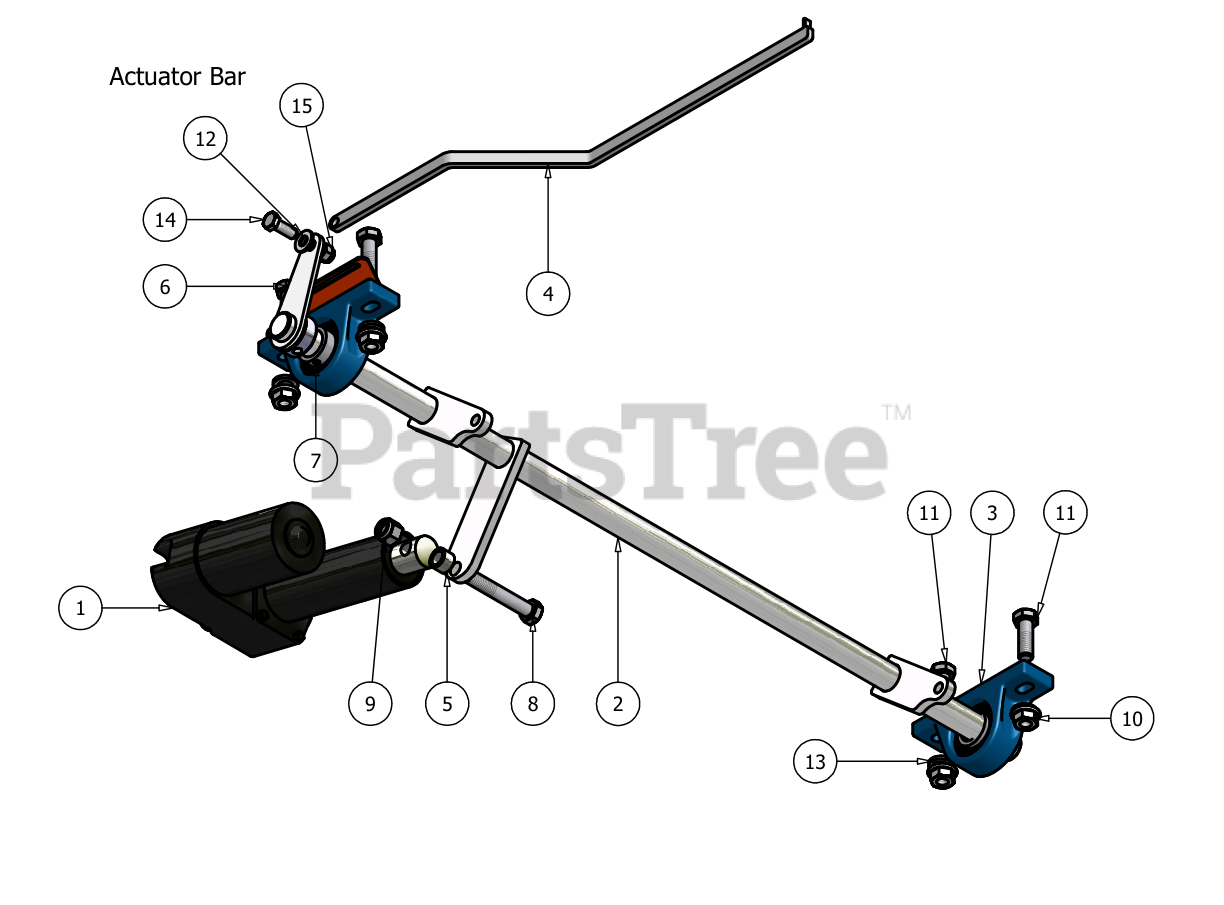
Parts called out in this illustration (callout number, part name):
2	Actuator Bar
3	1" Pillow Block
4	Height Indicator
5	1/2" x 1/2" Collar Spacer
6	2006 Height Indicator Lever
7	3/8" Set Screw
8	1/2" x 3" Hex Bolt
9	1/2" Nylock Nut
10	1/2" Flange Nut
11	1/2" x 1 1/2" Hex Bolt
12	.360 ID Plastic Washer
13	1/2" Lock Washer
14	3/8" x 1" Hex Bolt
15	3/8 Nylock Nut
